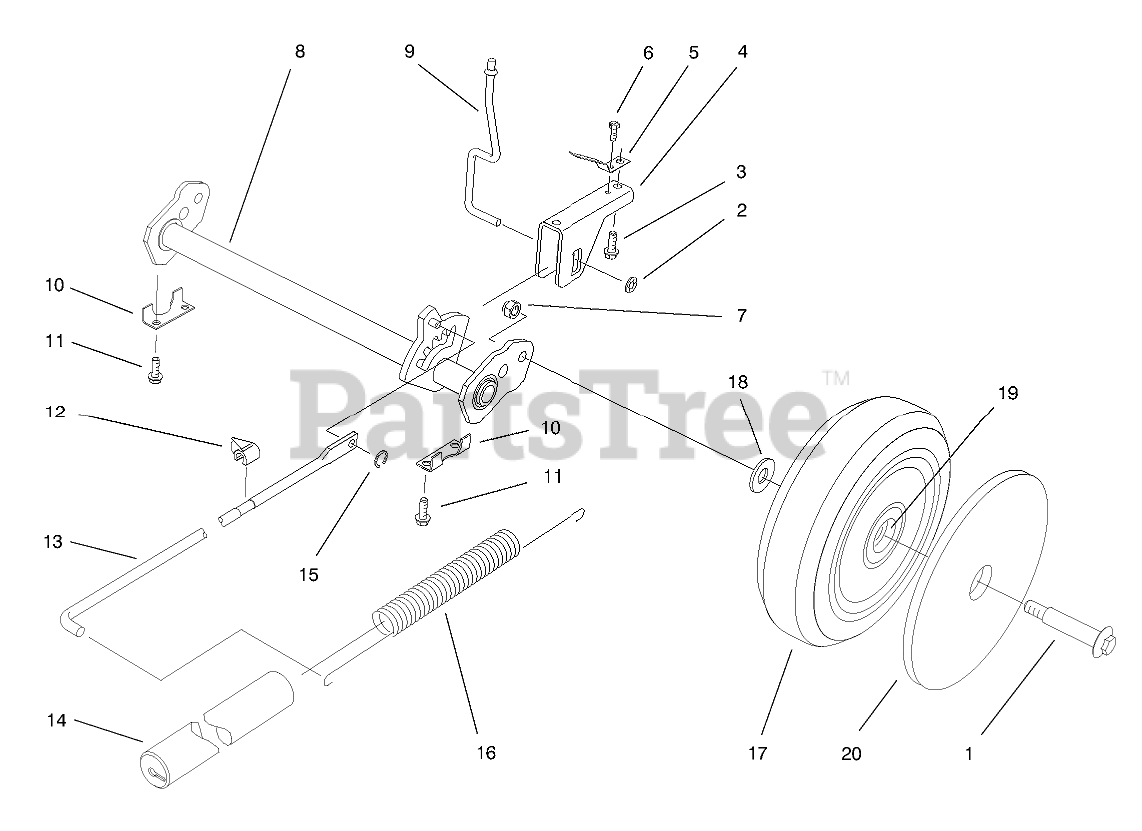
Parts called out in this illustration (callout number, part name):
1	BOLT-WHEEL
2	PUSHNUT
3	SCREW
4	SADDLE - HOC
5	SPRING - TRIGGER RET
6	SCREW 8 - 32 X 250
7	NUT-HEX
8	PIVOT ARM REAR WA
9	TRIGGER ROD
10	REAR SECURING PLATE
11	SCREW-HWH
12	INDICATOR-HEIGHT OF CUT
13	LINK ROD
14	COVER-SPRING
15	GRIP RING
16	SPRING-COUNTERBALANCE
17	Rear Wheel & Tire Assembly (Incl. Ref. # 19)
18	WASHER
19	BUSHING
20	COVER-WHEEL
